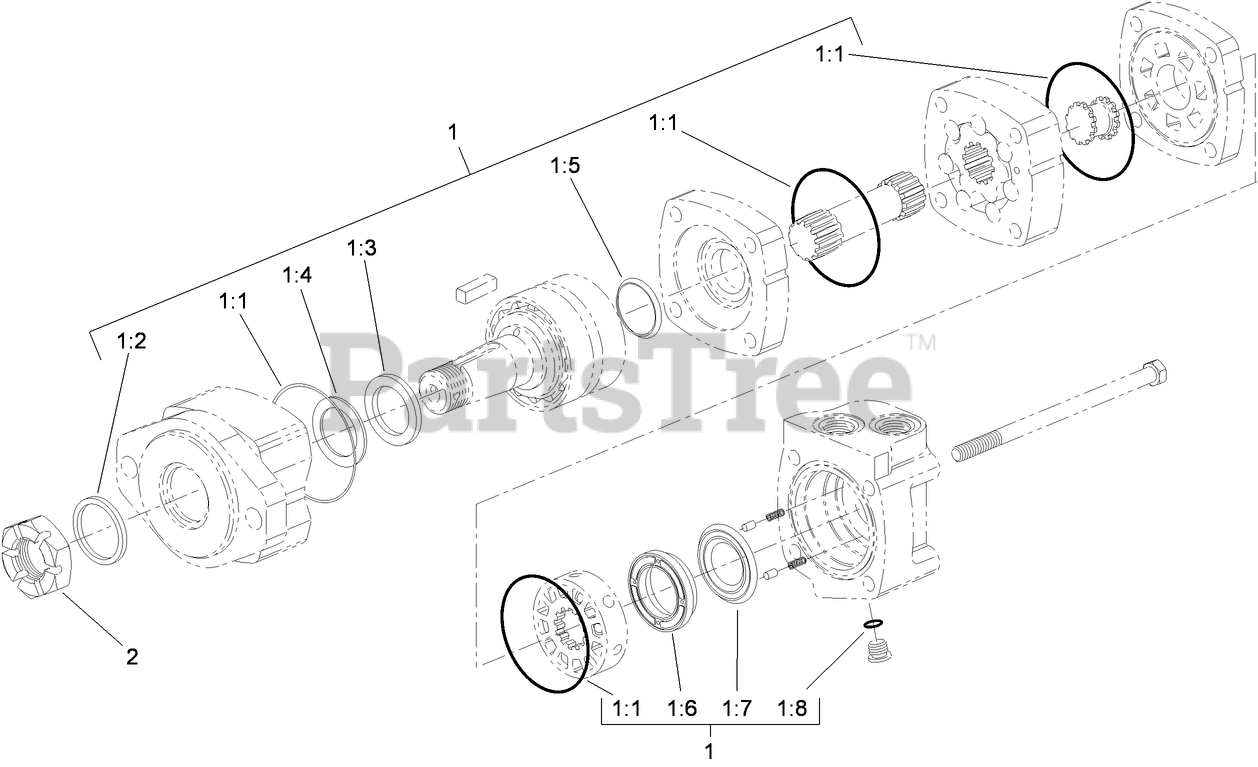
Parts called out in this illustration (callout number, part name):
1	SEAL KIT
1:1	SEAL
1:2	EXCLUSION SEAL
1:3	Outer Face Seal
1:4	Inner Face Seal
1:5	Shaft Face Seal
1:6	SHAFT SEAL
1:7	Back-Up Washer
1:8	HUB and BEARING ASM
